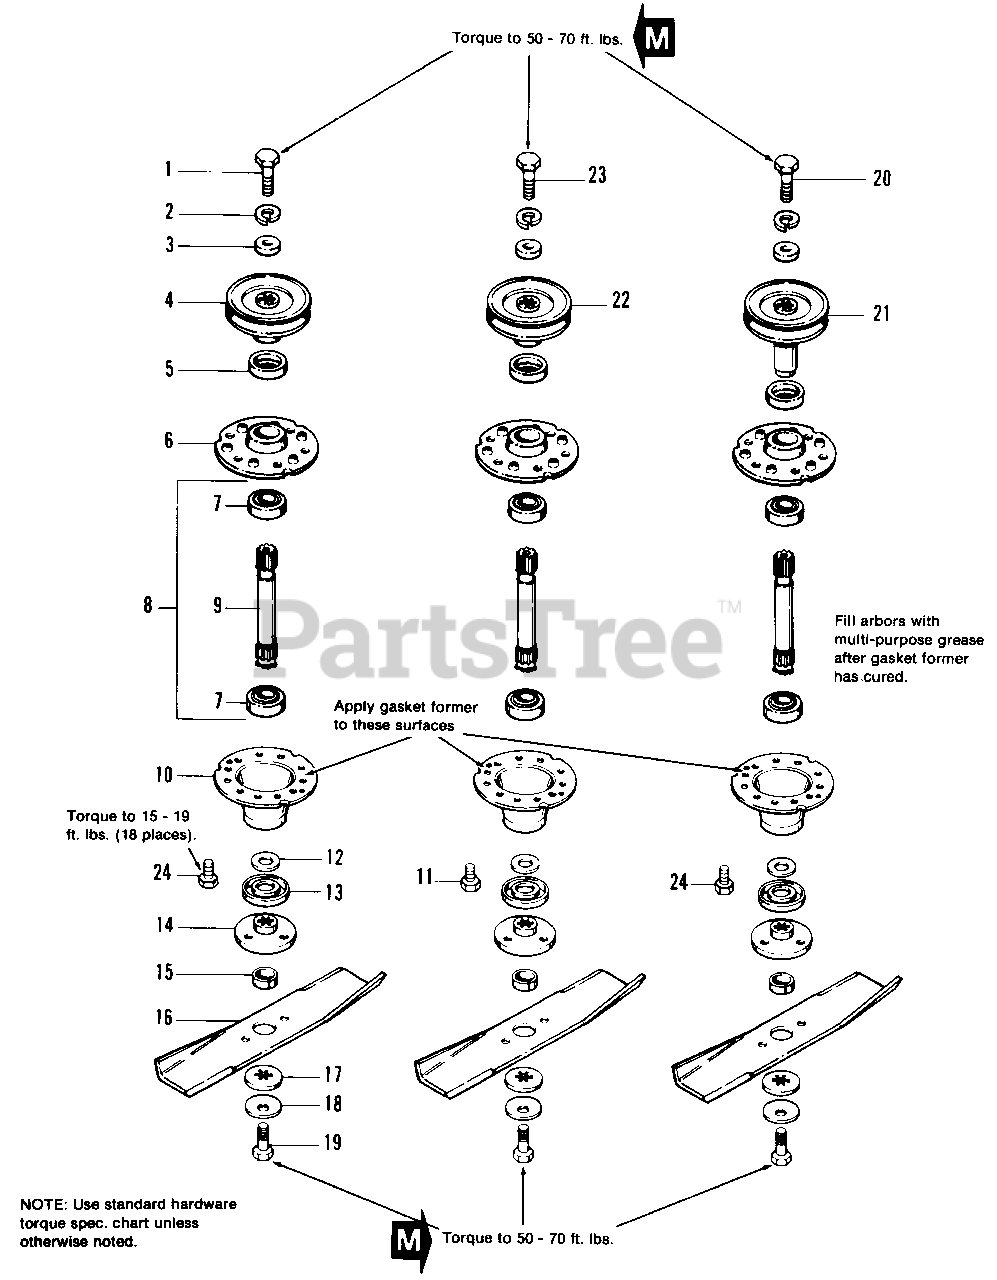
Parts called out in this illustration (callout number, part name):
1	CAPSCREW, Hex 7/16-14 x 1/2
2	LOCKWASHER, 7/16
3	WASHER, Plain, 29/64 x 1-1/4 x 1/4
4	PULLEY ASSY.
5	SHIELD, Bearing Upper, Arbor
6	HOUSING TOP
8	SHAFT & BEARING ASSY. (Incl. Ref. Nos. 7, 9 & 15)
9	SHAFT, Arbor (Incl. Ref. No. 15)
10	HOUSING, Bottom
11	SCREW, Hex, Taptite, 5/16-18 x 3/4
12	WASHER, Shim
13	SHIELD, Grass
14	ADAPTOR, Blade
16	BLADE, 42" Mower
16	BLADE, 48" Mower
17	WASHER, Spline
18	WASHER, Spring
19	CAPSCREW, Hex 7/16-14 x 1
20	CAPSCREW, Hex, 7/16-14 x 3-1/2
21	PULLEY ASSY.
22	PULLEY ASSY.
23	CAPSCREW, Hex, 7/16-14 x 1-3/4
24	SCREW, Hex Taptite, 5/16-18 x 1
